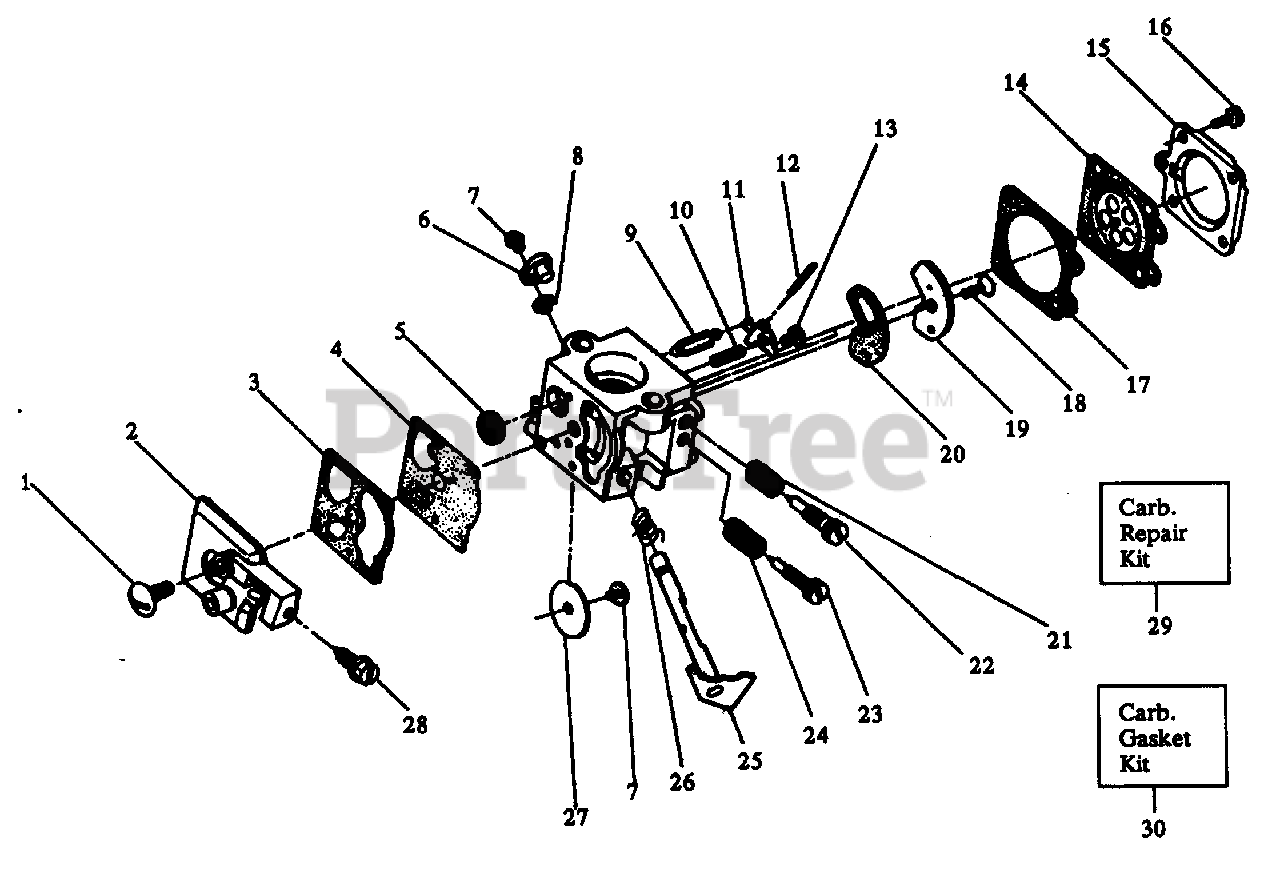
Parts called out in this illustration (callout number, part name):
1	Pump Cover Screw
2	Pump Cover Ass'y. (Inc.28)
3	Pump Gasket
4	Diaphragm Pump
5	Inlet Screen
6	Swivel Lever Ass'y.
7	Throttle Valve Screw
8	Throttle Shaft Clip
9	Inlet Needle Valve
10	Metering Lever Spring
11	Metering Lever
12	Metering Lever Pin
13	Metering Lever Pin Screw
14	Diaphragm Ass'y. Metering
15	Metering Diaphragm Cover
16	Metering Cover & Throttle Shaft Clip Screw
17	Metering Diaphragm Gasket
18	Circuit Plate Screw
19	Circuit Plate
20	Circuit Plate Gasket
21	Hi Speed Needle Spring
22	Hi Speed Needle
23	Idle Needle
24	Idle Needle Spring
25	Throttle Shaft Ass'y.
26	Throttle Return Spring
27	Throttle Valve
28	Idle Adjustment Screw
29	Kwik Repair Kit
30	Gasket/Diaphragm Kit
